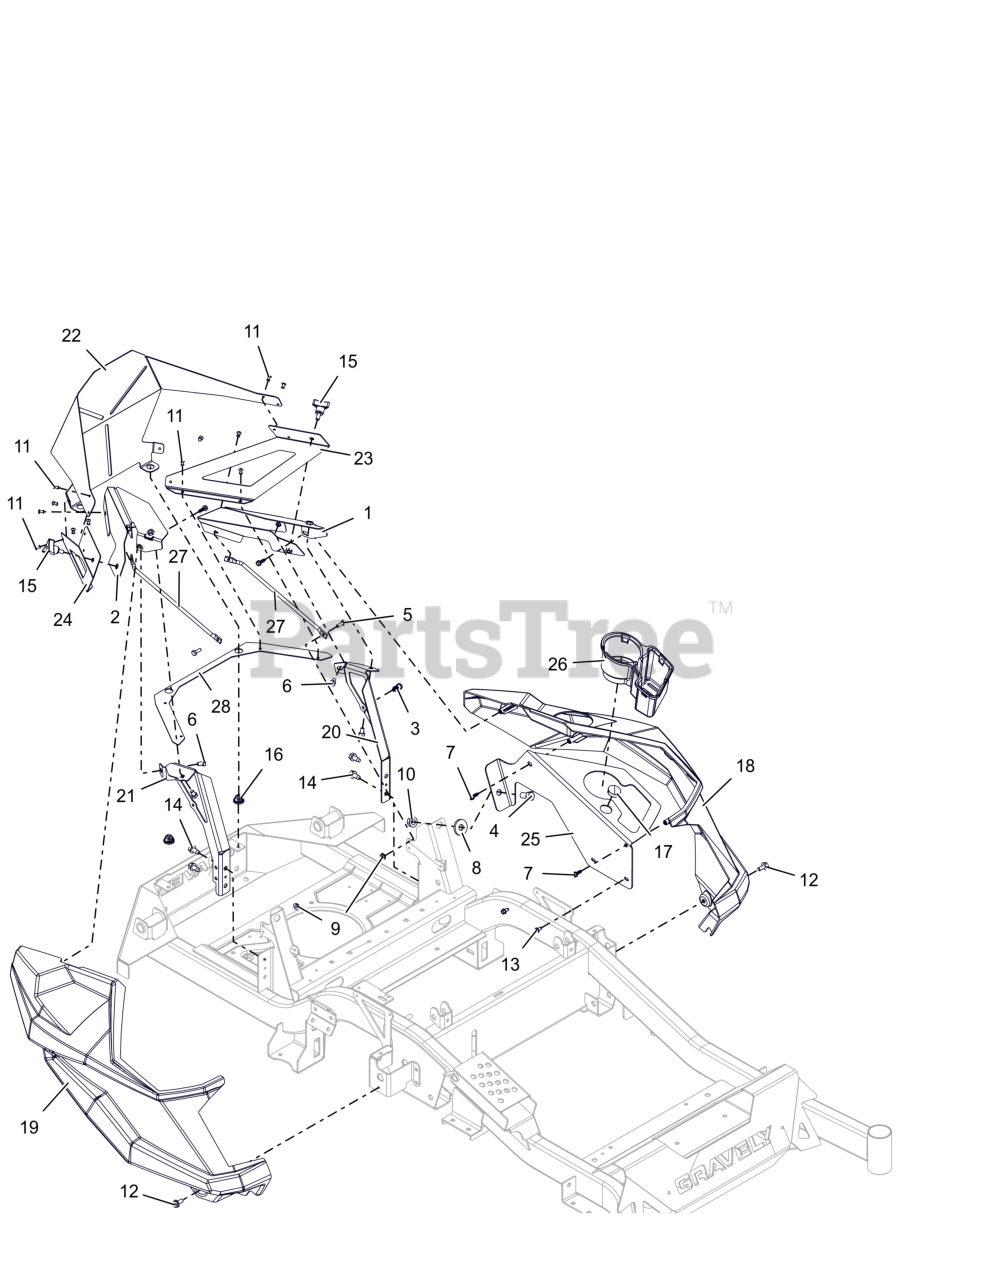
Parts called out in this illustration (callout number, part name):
1	PANEL, LH (RED)
2	PANEL, RH (RED)
3	CLIP, CABLE GUIDE
4	BLT, HEX .50-13X1.00 G5 ZCC
5	BLT, HEX .25-20X.75 G5 ZCC
6	BLT, HEX .31-18X.50 GR5 ZCC
7	SCR, PLASTITE-HWH 0.25 X 0.75 ZC120
8	WASHER- FLT .562X1.50X.187 ZCC
9	NUT-LK-CTR-FLG .25-20 ZC120
10	NUT-LK-TOP-FLG .500-13 GF ZCC
11	RIVET, #66 STEEL POP PD BLACK
12	BLT, SERHFWH 0.312-18X0.75 GR5 ZCC
13	SCR-TAP .25-20X.50 HWH ZCC
14	SCR,TAP .375-16X.75 HWH TR ZCC
15	KNOB,WING STUD 5/16-18 X .75
16	GROMMET, 10MM BOLLHOFF
17	PLUG, HOLE 1.125 DOMED
18	FENDER, LH
19	FENDER, RH
20	BRKT, LH FENDER MTG (RED)
21	BRKT, RH FENDER MTG (RED)
22	WRAP, REAR (BLACK)
23	WRAP, REAR - LH (RED)
24	WRAP, REAR - RH (RED)
25	PANEL, HD CUPHOLDER (RED)
26	HOLDER, CUP
27	ROD, STIFFENER
28	STIFFENER, BACK WRAP (RED)
